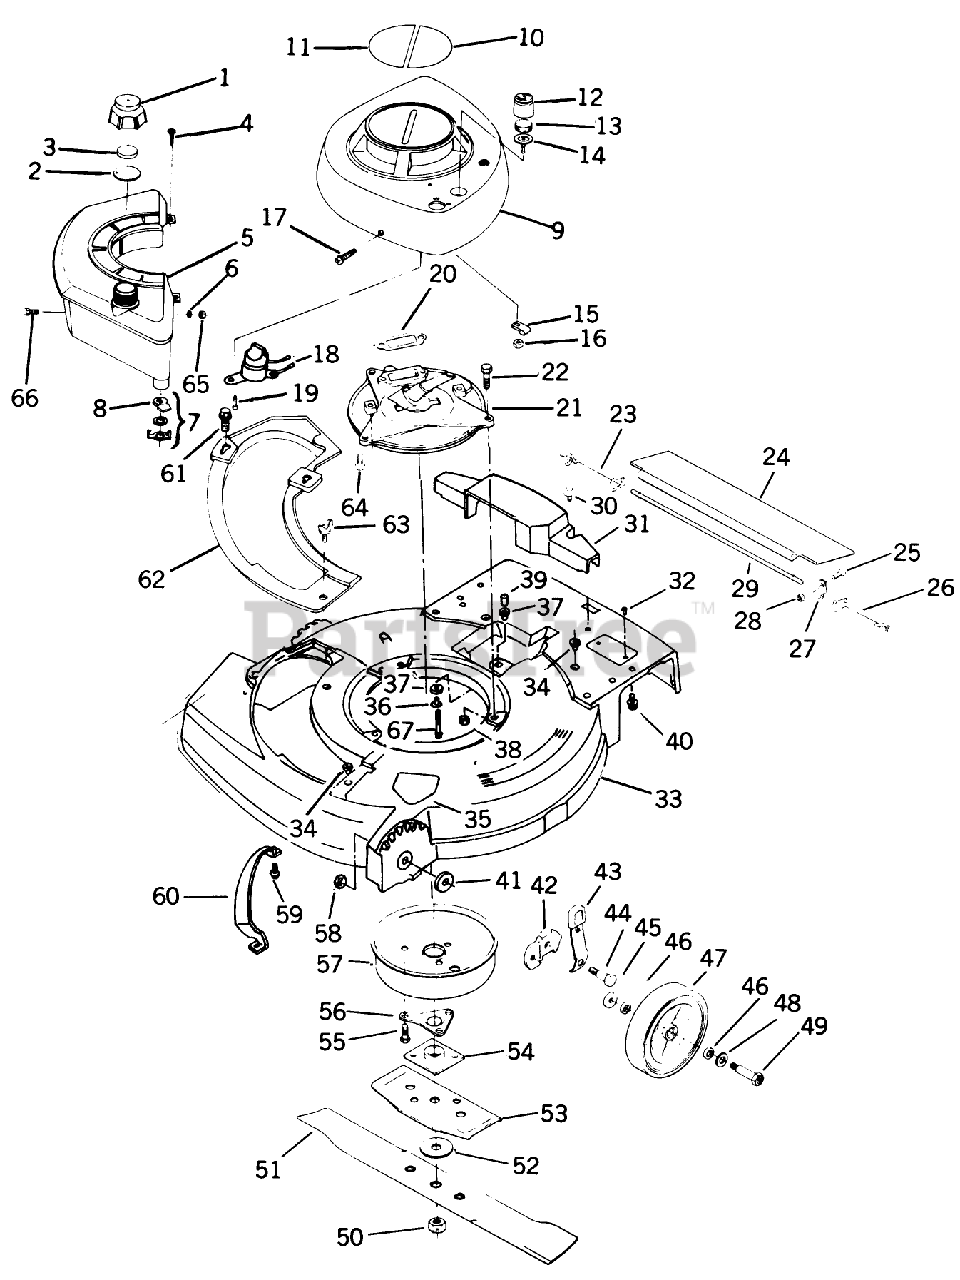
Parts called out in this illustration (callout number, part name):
2	GASKET S
3	BAFFLE - FOAM SM
4	SCREW F
7	SHUT OFF VALVE KIT
13	FILTER S
16	LOCKNUT S
17	SCREW F
22	SCREW
23	SPRING;TRAILING SHIELD RH
24	SHIELD
26	SPRIG T/SHLD ASOC
27	CLAMP ROD KMC
28	LOCKNUT E
29	ROD 21" ADVANCE
30	SCREW SEMS TRM HEX HD
36	SPACER ECK PRES
37	GROMMET
38	NUT-LOCK F
39	SPACER
40	SCREW
41	WASHER
45	WASHER WROUGHT
46	WASHER
47	WHEEL & TIRE KIT
48	SPACER
49	BOLT WHEEL
50	NUT-BLADE
52	WASHER
54	PLATE AND COLLAR ASM
55	SCREW
56	SUPPORT F
58	LOCKNUT
60	BAR-TOE
63	WING SCREW LAWRE
64	SCREW V
